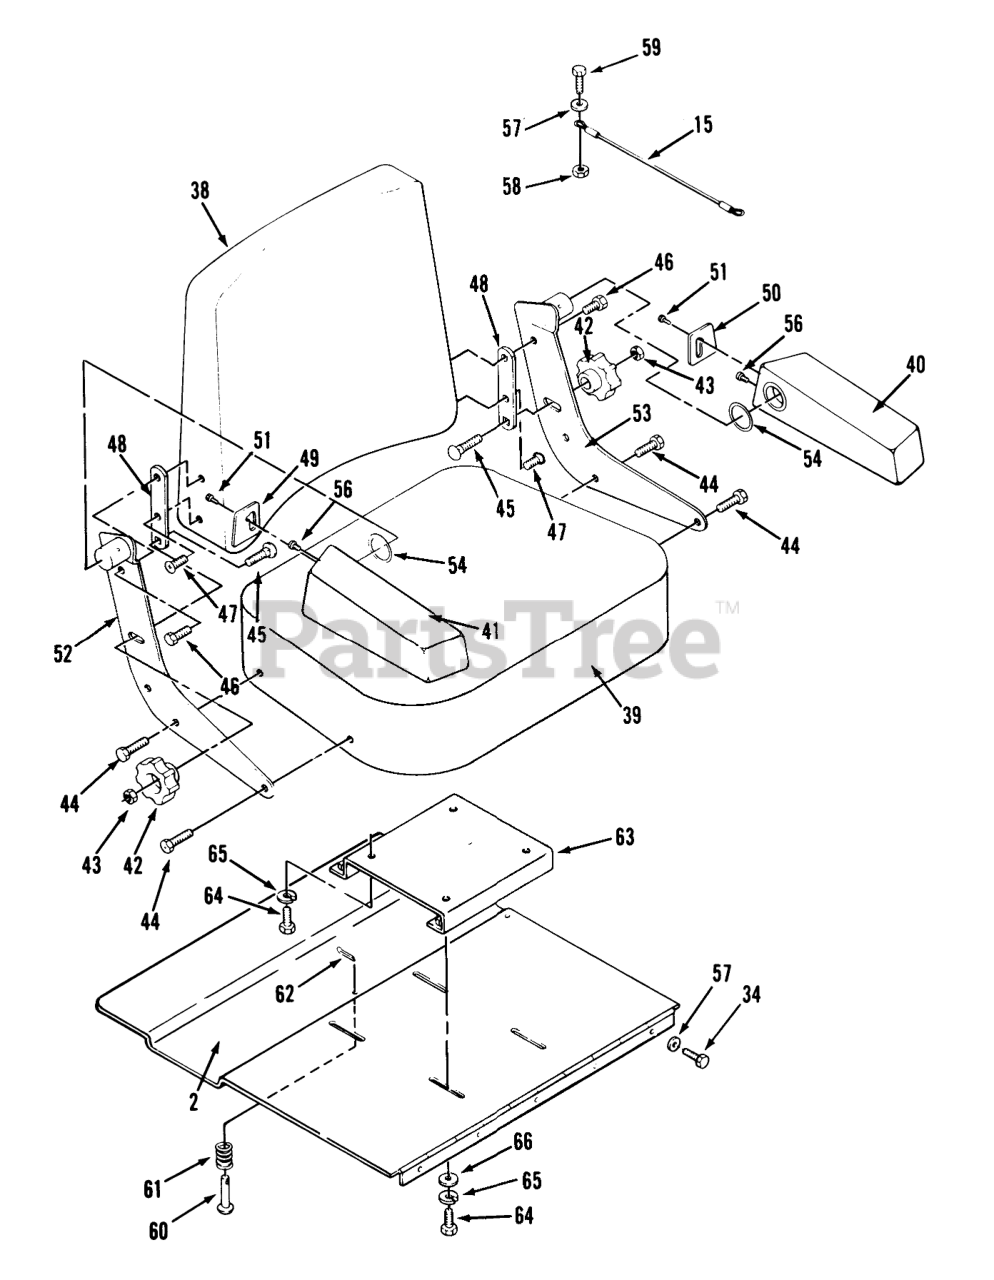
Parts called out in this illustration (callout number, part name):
2	Bracket-Seat Mounting
15	Cable
34	Bolt
38	Seat Back
39	Seat Bottom
40	ARM REST LH
41	ARM REST RH
42	Knob-Lumbar Control
43	LOCK NUT
44	Bolt
45	Bolt
47	Screw-Phillips Hd
48	Lumbar Friction Plate
49	ARM REST PLATE RH
50	ARM REST PLATE LH
51	SCREW PAN HD 10-16X5
52	Back Support LH
53	BACK SUPT LH
54	WASHER
56	SHCS 1/4-20 X 1/2
57	WASHER
58	NUT-LOCK, NI
59	Bolt
61	SPRING-COMPRESSION
62	PIN-COTTER
63	ASS'Y-SUPPORT SEA B
64	SCREW-HEX HD CAP
65	LOCKWASHER
66	WASHER-FLAT
